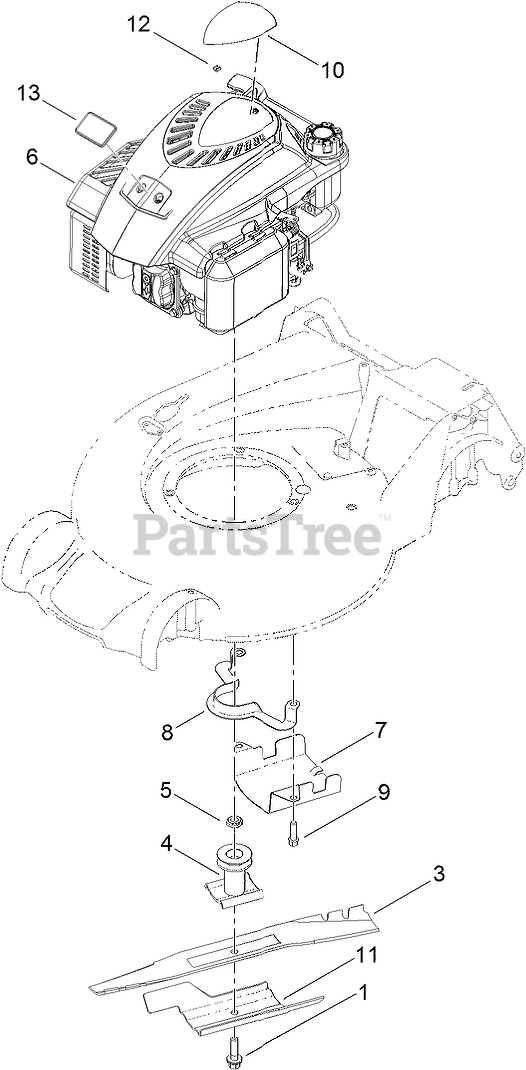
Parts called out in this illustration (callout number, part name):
1	BOLT-BLADE
4	DRIVER-BLADE
5	Spacer-Driver
6	ENGINE-1P65FC
7	SHIELD-GRASS
8	GUIDE-BELT
9	SCREW-MOUNT, ENGINE
10	DECAL-SHROUD
11	Accelerator-Blade
12	STOP-ROPE
13	PLATE-LOGO
